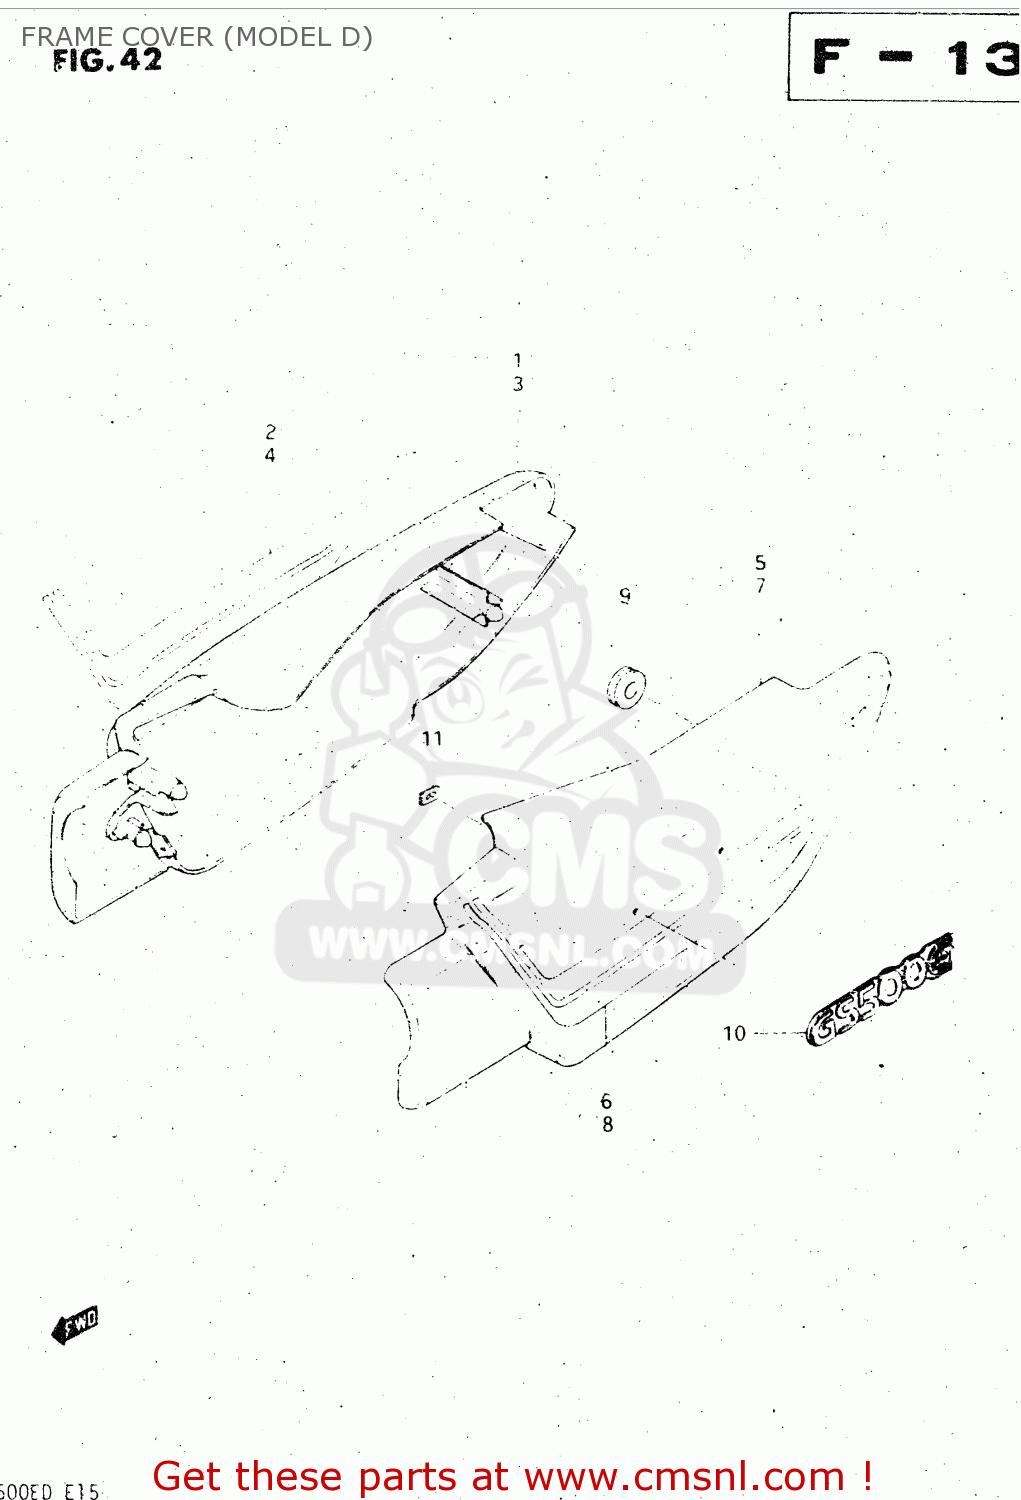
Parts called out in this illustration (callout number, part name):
1	COVER, FRAME RH (RED)
2	TAPE, RH
3	COVER, FRAME RH (BLUE)
4	TAPE, RH
5	COVER, FRAME LH (RED)
6	TAPE, LH
7	COVER, FRAME LH (BLUE)
8	TAPE, LH
9	CUSHION
10	EMBLEM
11	NUT
